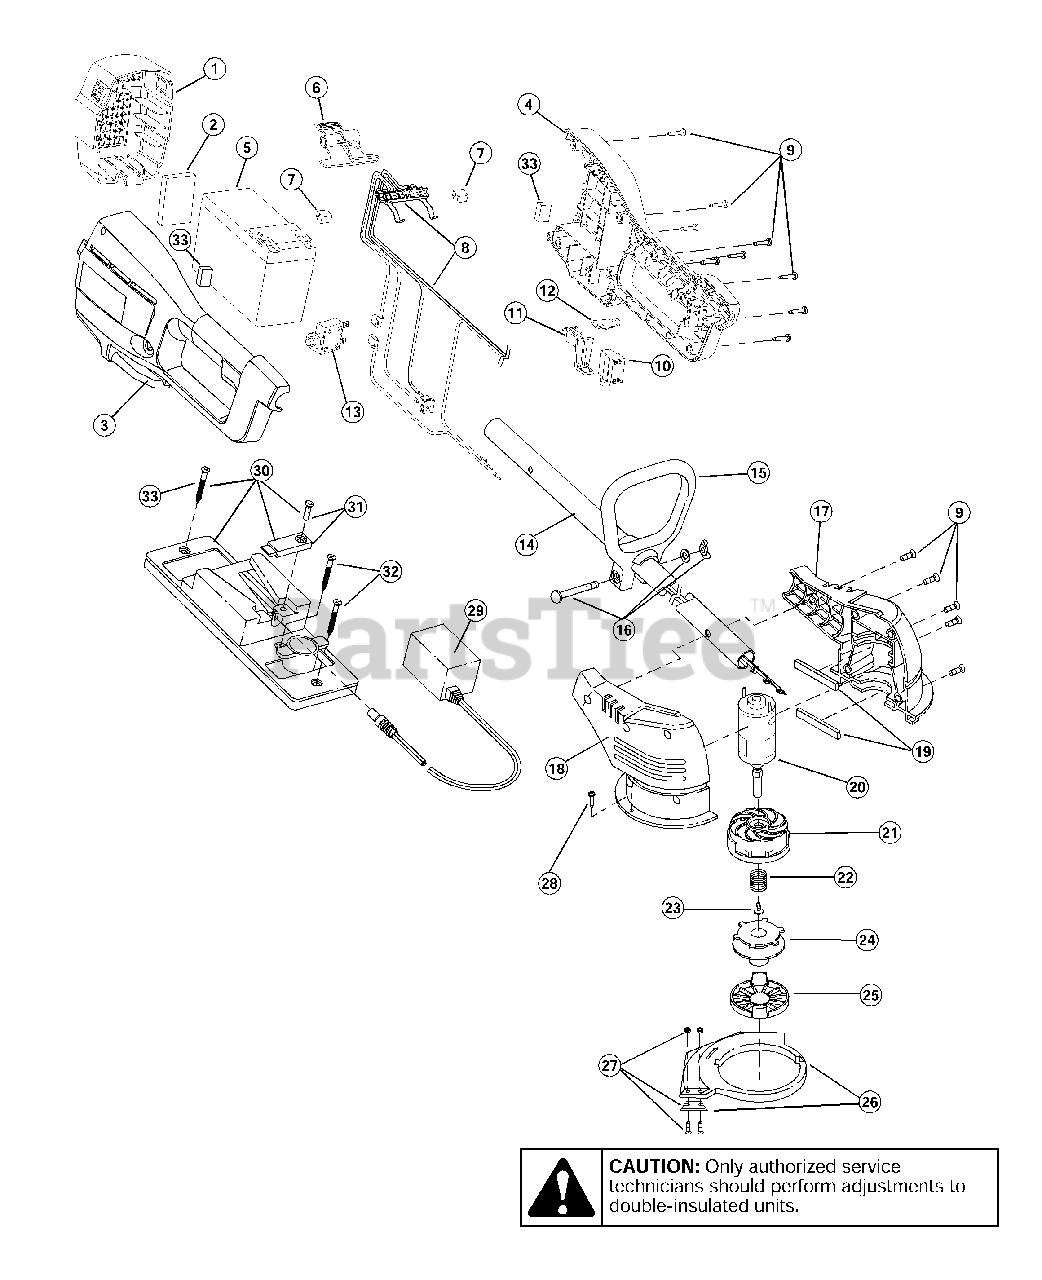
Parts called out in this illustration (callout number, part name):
1	Battery Door
3	Right Battery Housing
4	Left Battery Housing
5	12 Volt Battery
6	Battery Latch
7	Terminal Spacer
8	Wiring Harness Assembly
9	Housing Screw
10	Switch Assembly
12	Lock-Off Button
13	Circuit Breaker
14	Motor Wire Tube
15	D-Handle
16	Handle Hardware
17	Left Motor Housing
18	Right Motor Housing
20	Motor with Shaft
21	Outer Spool and Eyelet/Motor Fan
24	Inner Reel with .080" Line
25	Reel Cover
26	Guard and Blade Assembly
27	Blade Assembly
28	Guard Screw
29	12 Volt Charger
30	Charging Station Stand
31	Barrel Clamp with Screw
32	Mounting Screw
33	Front Battery Pads
